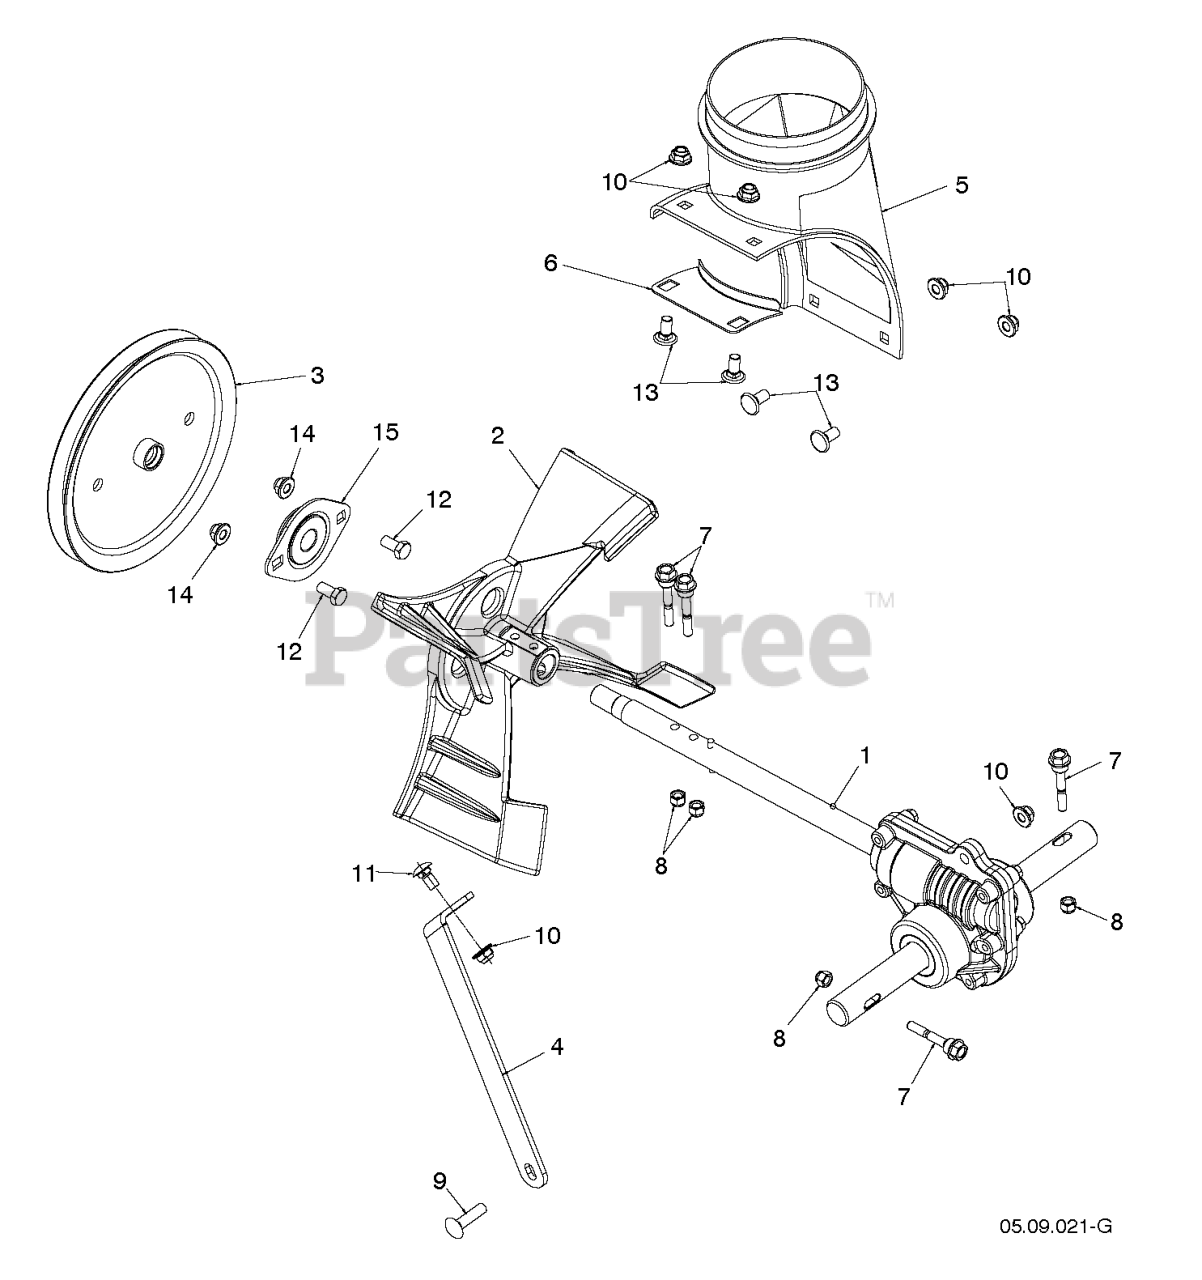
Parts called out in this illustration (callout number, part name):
1	GEAR BOX ASM CAST
2	IMPELLER CAST.IRON.12IN MS 417
3	PULLEY SCREW ON 7.9
4	SUPPORT.GEARBOX.LS.498
5	CHUTE.DISCHARGE.BASE
6	BRACKET, CORNER DISCHARGE
7	BOLT.1/4-20 X 1-13/16 SHEAR
8	LOCKNUT.NYLOC.1/4-20
9	BOLT.CARRIAGE.5/16-18
10	NUT HEX FLG NYLOCK BLK 5_16-1
11	BOLT CAR BLK 5/16-18 X 5/8
12	BOLT, HEX HEAD 5/16-18
13	BOLT CARR WAFER BLK 5_16-18 X
14	NUTNYLOK.FLRANGE.5/16-18
15	BEARING FLANGE
